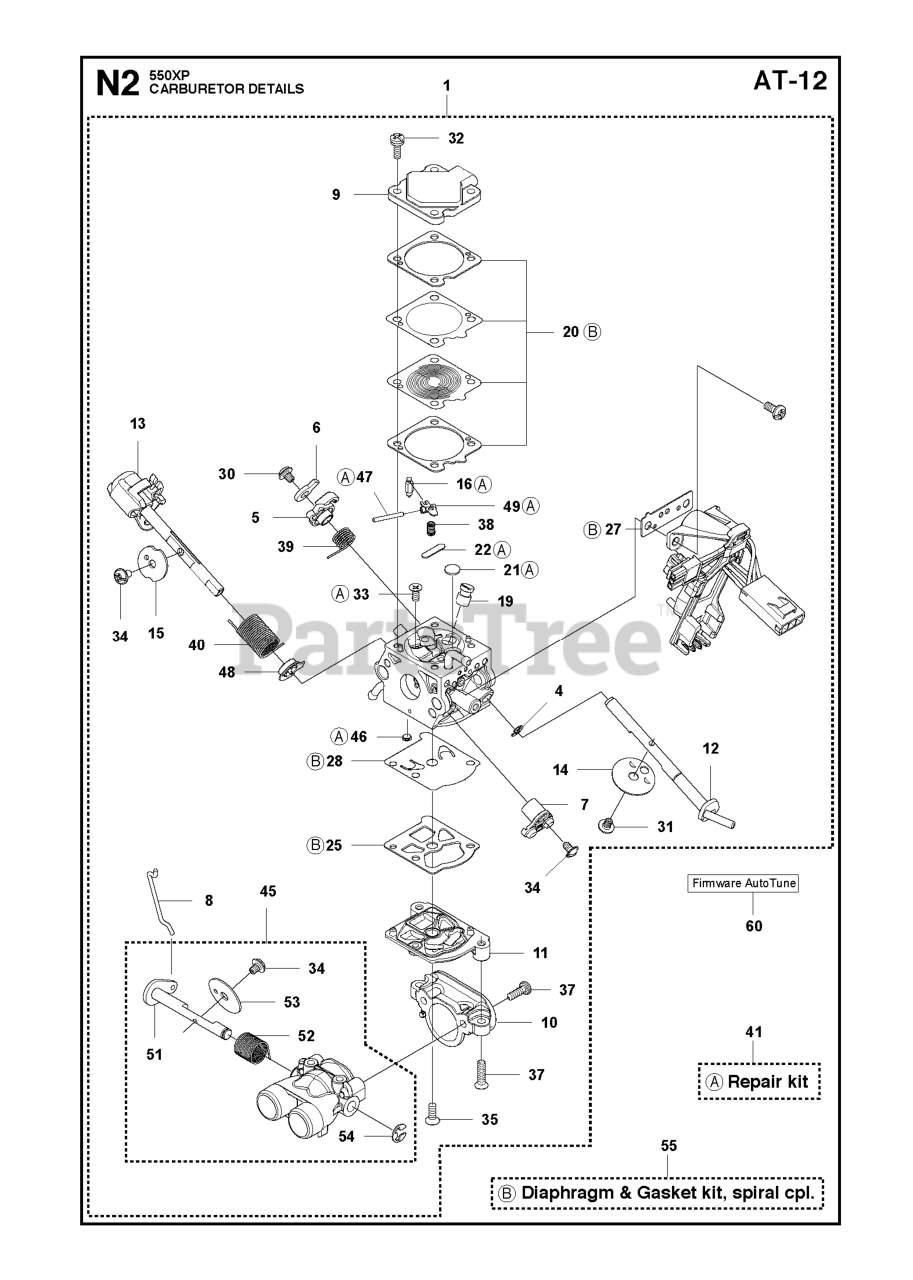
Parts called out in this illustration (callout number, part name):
7	THROTTLE LEVER ASSY
12	SHAFT ASSY
15	VALVE THROTTLE
16	INLET NEEDLE
19	NOZZLE ASSY
21	PLUG WELCH
29	DIAPHRAGM ASSY
31	SCREW
41	REPAIR KIT
45	THROTTLE VALVE ASSY
46	FUEL INLET SCREEN
47	FULCRUM PIN
51	SHAFT ASSY
54	E CLIP
55	GASKET KIT
